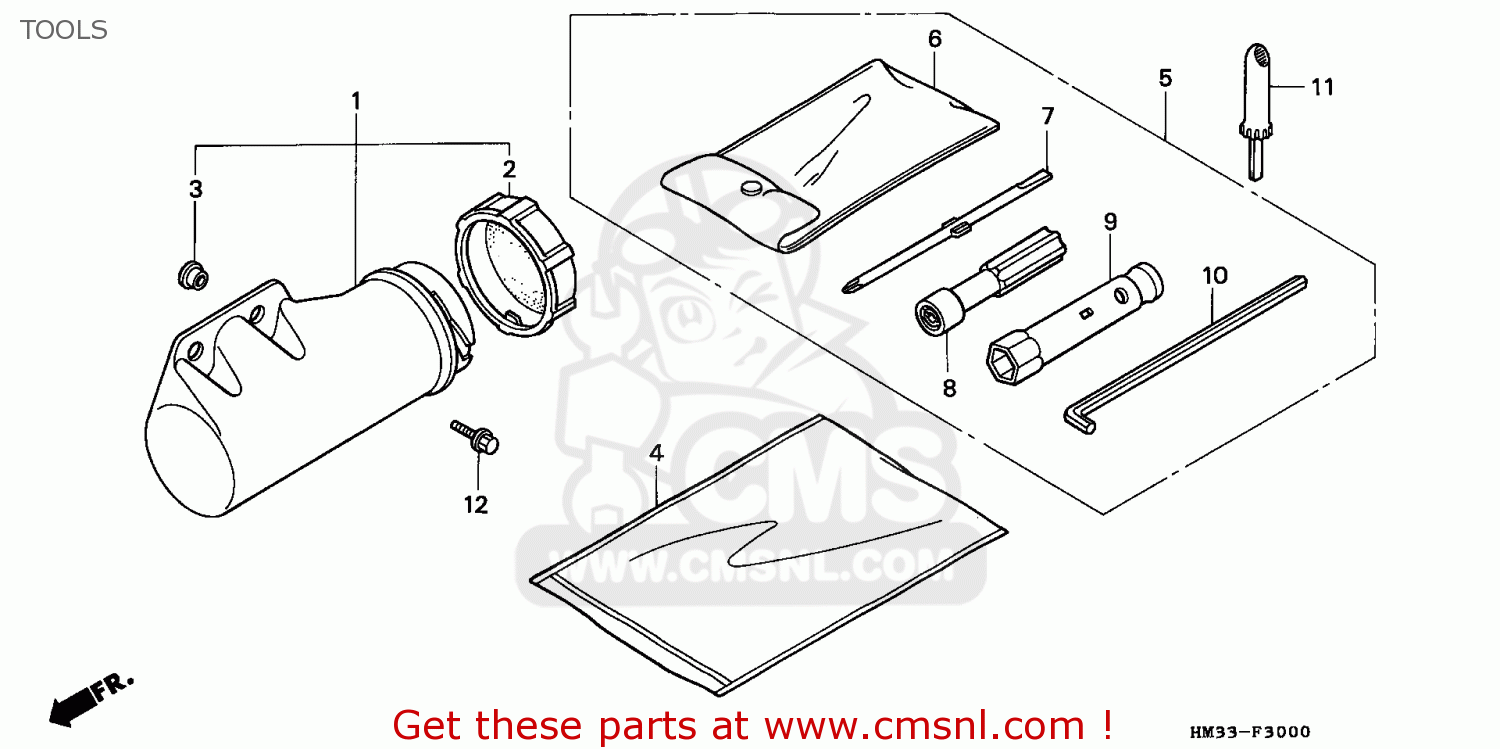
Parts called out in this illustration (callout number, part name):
1	BOX ASSY,TOOL
2	CAP,TOOL BOX
3	COLLAR,TOOL BOX
4	BAG, OWNER'S MANUAL
5	TOOL SET ASSY.
6	TOOL BAG,170
7	SCREWDRIVER
8	GRIP,DRIVER
9	BOX WRENCH,P18
10	WRENCH,HEX.,6MM
11	GAUGE,TIRE PRESSU
12	BOLT FLANGE 8X20
